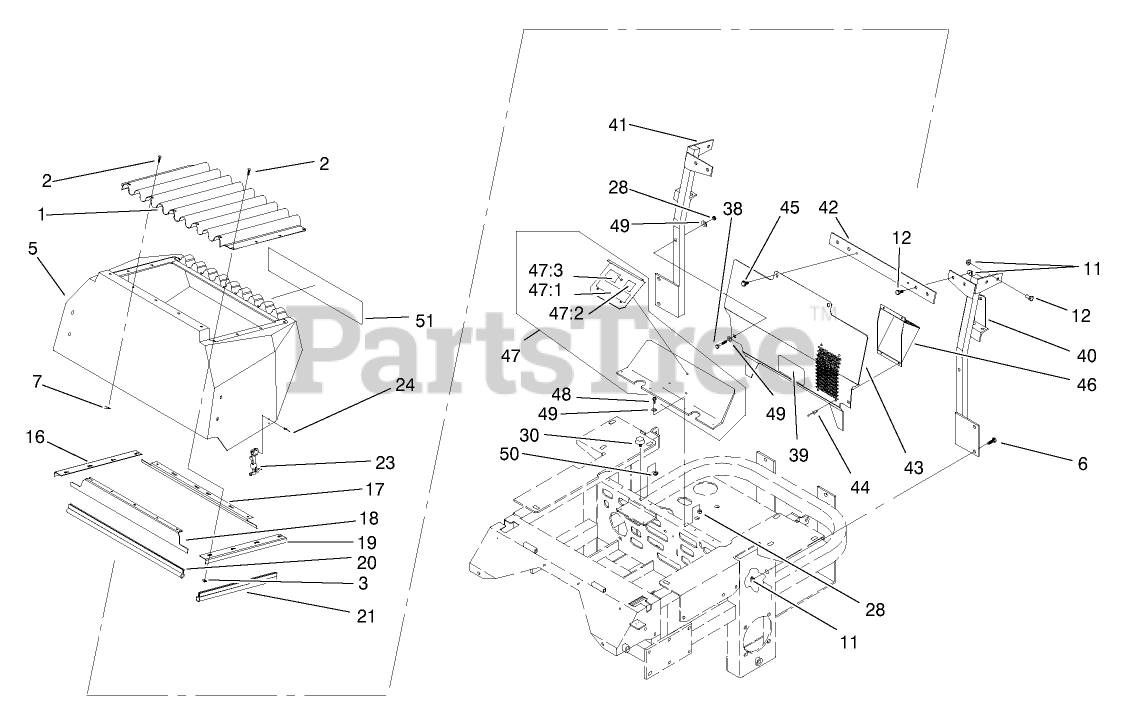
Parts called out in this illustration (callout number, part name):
1	Screen-Intake, Radiator
2	Rivet
3	WASHER-FLAT
5	Hood-Engine
6	SCREW-HH
7	Washer
11	NUT-HF
12	SCREW-HH
16	Angle-Trim, Radiator
17	Angle-Trim, Radiator
18	Angle-Trim, Radiator
19	Angle-Trim, Radiator
20	Seal-Trim
21	Seal-Trim
23	Latch-Rubber
24	Rivet
28	NUT-LOCK
30	Bumper
38	SCREW-HH
39	Decal-Belt Routing
40	Radiator Brace ASM, LH
41	Radiator Brace ASM, RH
42	Crossbar
43	Deflector-Air
44	Rivet-Pop
45	Screw-Tapping
46	Plenum-Intake, Air
47	Shield ASM
47:1	Decal-Belt, Drive
47:2	Decal-Guard
47:3	Decal-Important
48	SCREW-HH
49	Washer-Flat
50	NUT-HF
51	DECAL-Z MASTER LIQUID COOLED
